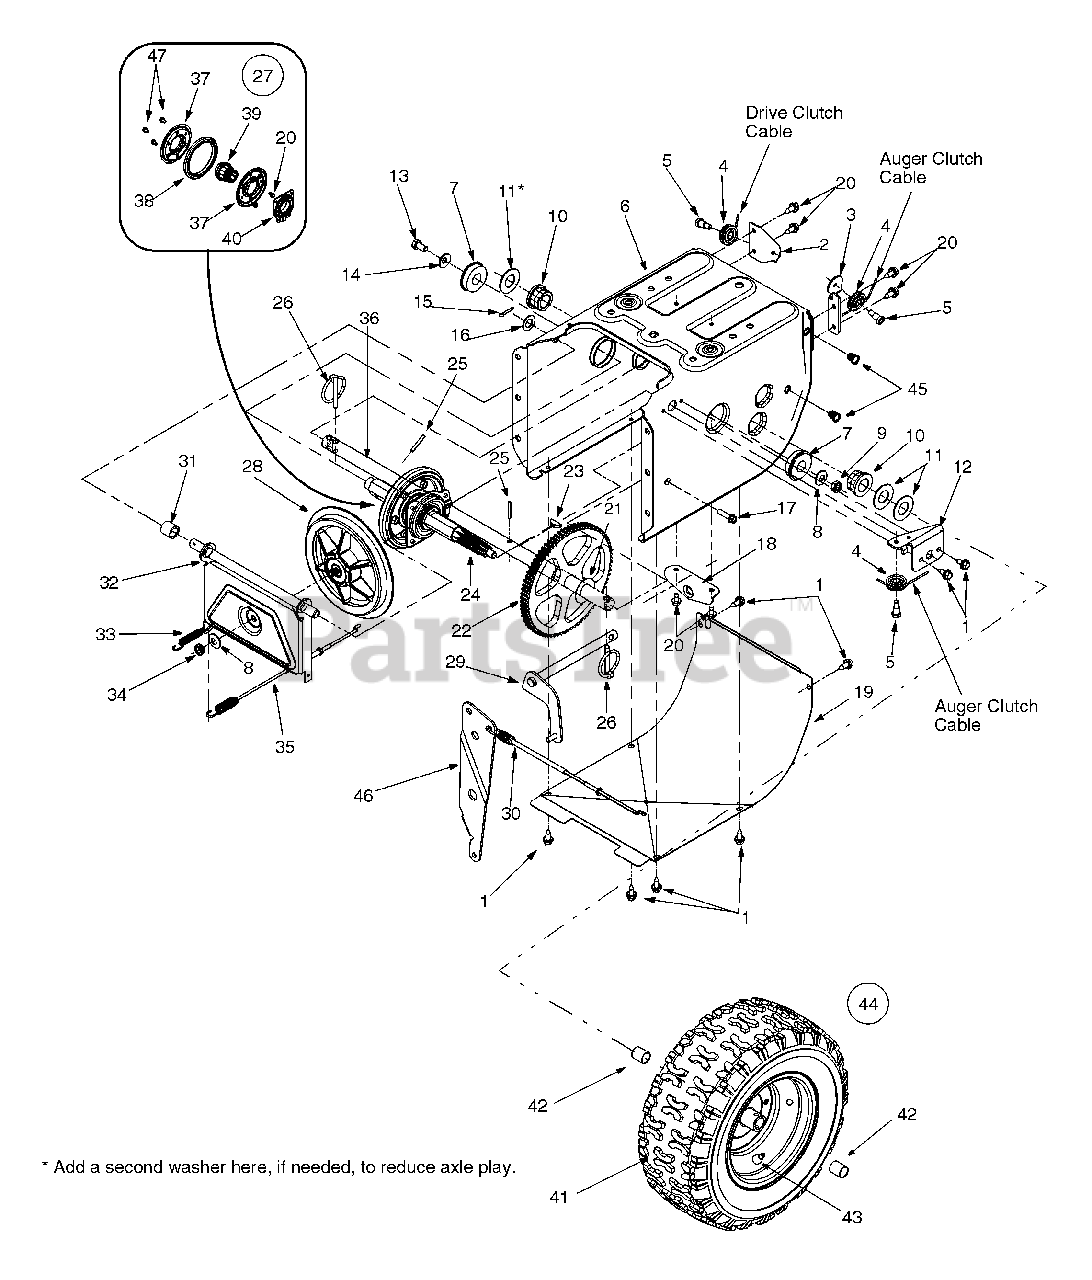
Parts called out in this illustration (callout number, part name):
1	Hex Screw 1/4-20 x .625
5	Shoulder Screw 1/4-28 x .375
8	Bell Washer
9	Lock Jam Nut, 3/8-24
10	Hex Flange Bearing
11	Flat Washer, .76 x 1.49 x .06
14	Bell Washer .340 ID x .872 OD
15	Cotter Pin, .125 x .75
16	Flat Washer .536 ID x .930 OD
17	Hex Washer Screw 1/4-20
21	Flat Washer .760 ID x .50 OD
22	Gear, 80-tooth
23	Key, 3/16 x 3/4
24	7-Tooth Shaft
25	Roll Pin
26	Clik Pin
27	Friction Wheel Assembly
28	Friction Wheel Disc
29	Wheel Shift Rod Assembly
30	Drive Cable
34	Jam Nut, 3/8-24
35	Drive Cable
36	Wheel Axle, .750 x 22.21
37	Friction Wheel Side Plate
38	Friction Wheel Rubber
39	Friction Wheel Hub
40	Friction Wheel Bearing
42	Sleeve Bearing, .75 x .87 x 1
43	Air Valve
47	Hex Washer Screw 1/4-20
